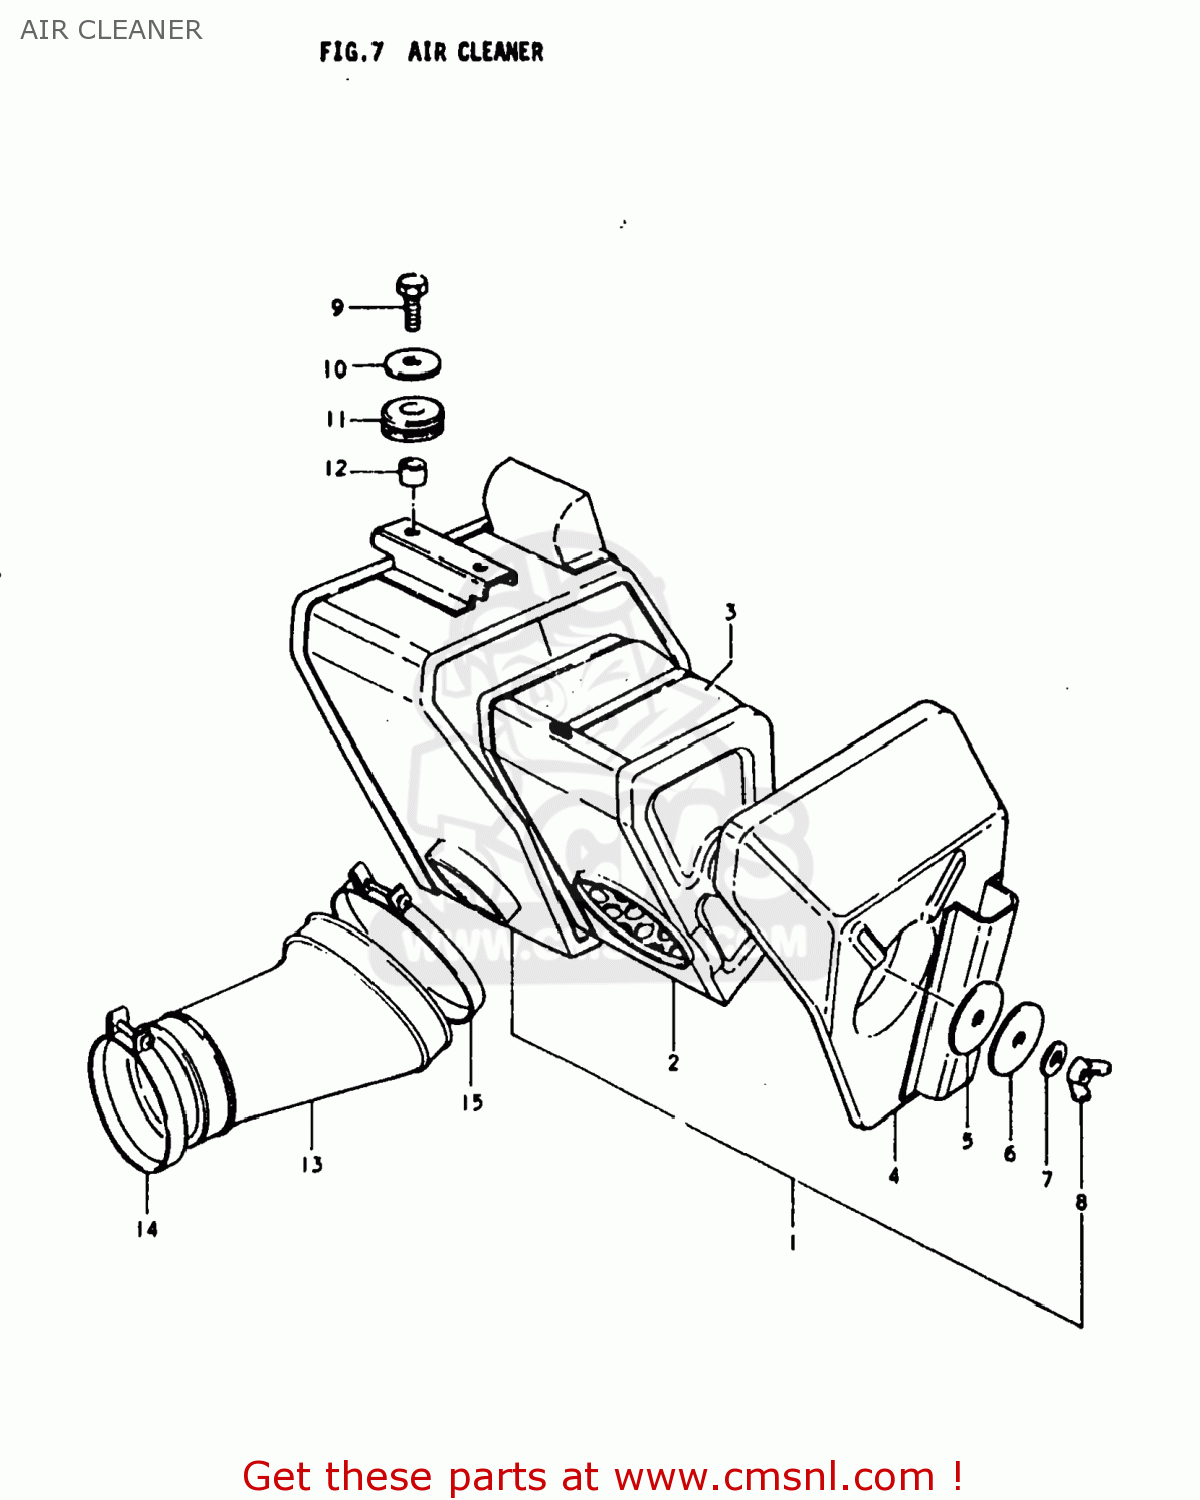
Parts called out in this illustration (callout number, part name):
1	CLEANER ASSEMBLY,AIR
2	FILTER ASSY
3	FILTER
4	CAP,AIR CLEANER
5	SEAL
6	WASHER,AIR CLEANER ELEMENT
7	WASHER
8	NUT
9	BOLT, UPPER
10	WASHER (6.5X20X1.2)
11	CUSHION
12	SPACER (7X9X7)
13	HOSE,CARBURETOR AIR INLET
14	CLAMP
15	CLAMP
